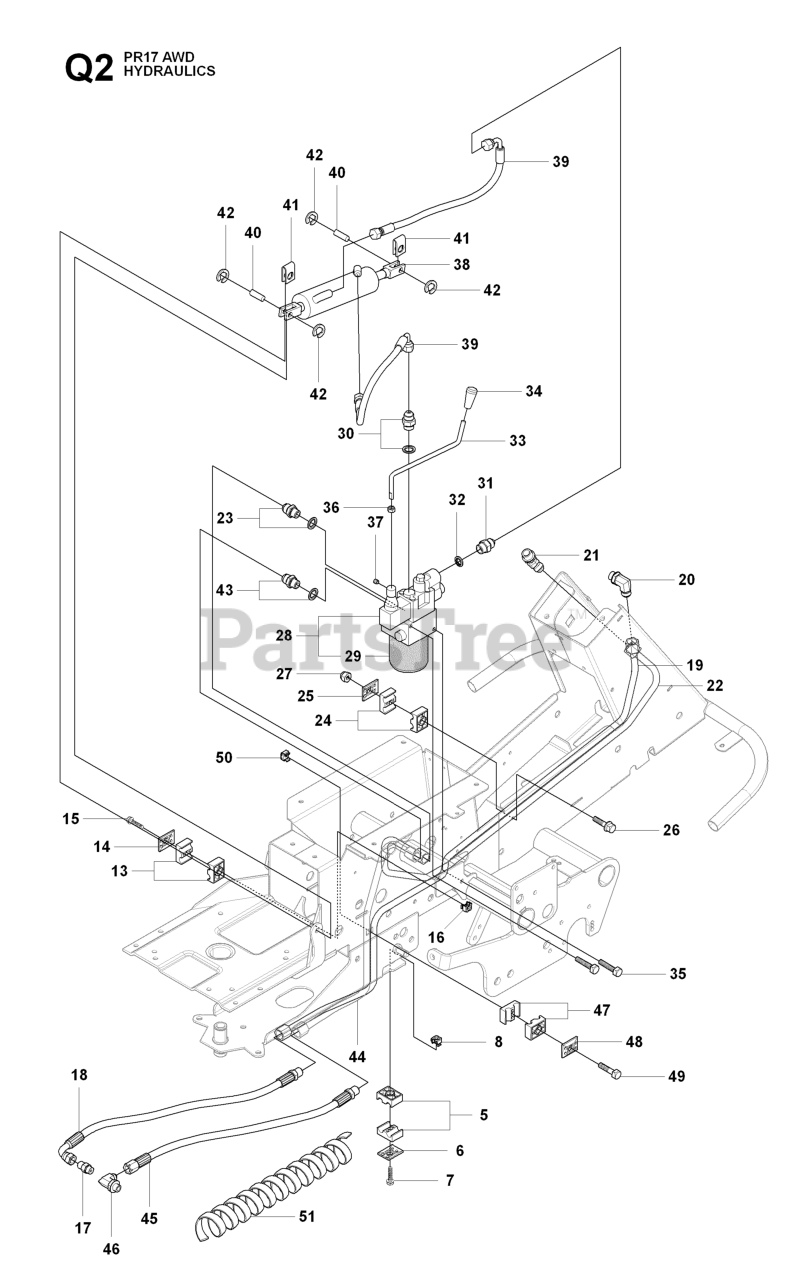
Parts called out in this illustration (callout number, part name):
5	PIPE CLAMP
6	COVER PLATE
7	SCREW EHHFM
13	PIPE CLAMP
24	PIPE CLAMP
27	LOCKNUT M6
29	FILTER
35	REPL BY 725 24 49-51
36	NUT
42	RETAINING RING SGA 10
47	PIPE CLAMP
51	HOSE GUARD D=43 L=400
